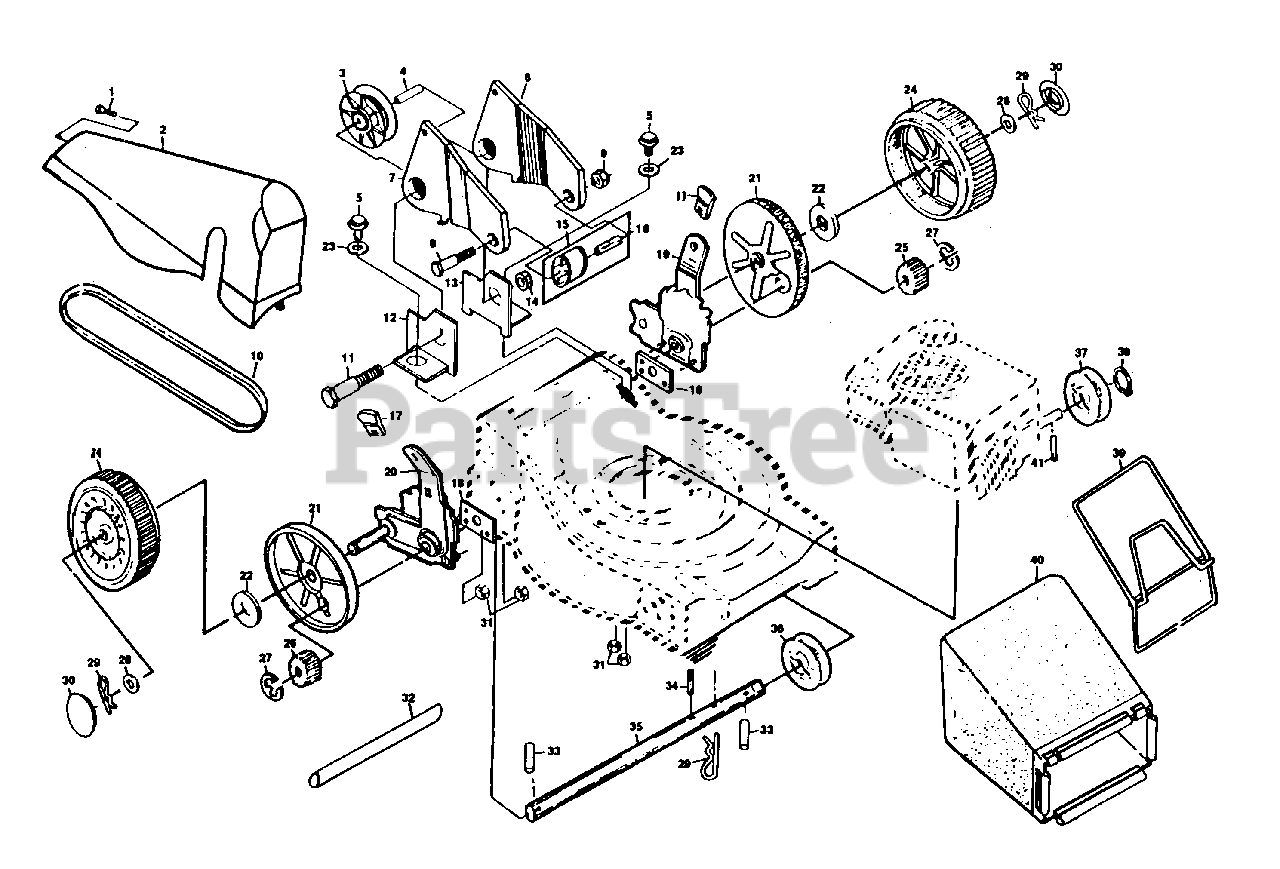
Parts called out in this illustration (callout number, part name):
1	Hex Washer Hd. Screw #10-24 x 1/2 (AYP part number)
2	Drive Cover (AYP part number)
3	Idler Pulley (AYP part number)
4	Pulley Spacer (AYP part number)
5	Screw Hex Hd. Mach. 1/4-20 x .75 (AYP part number)
6	Idler Bracket (Left) (AYP part number)
7	Idler Bracket (Right) (AYP part number)
8	Hex Head Bolt 1/4-20 x 1-1/2 (AYP part number)
9	Locknut 1/4-20 (AYP part number)
10	Drive Belt
11	Hex Head Bolt 5/16-18 x 1-1/2 (AYP part number)
12	Pivot Bracket (Right) (AYP part number)
13	Pivot Bracket (Left) (AYP part number)
14	Locknut 5/16-18 (AYP part number)
15	Idler Assembly Kit (Inc. 16)
16	Idler Spacer (AYP part number)
17	Selector Knob (AYP part number)
18	Spacer Plate (AYP part number)
19	Selector Assembly (Left)
20	Selector Assembly (Right)
21	Dust Cover
22	Washer (AYP part number)
23	Flat Washer (AYP part number)
24	Wheel & Tire Assembly 9.0 x 2.0 (AYP part number)
25	Drive Pinion (Left) (AYP part number)
26	Drive Pinion (Right) (AYP part number)
27	E-Ring (AYP part number)
28	Washer (AYP part number)
29	Retainer Clip (AYP part number)
30	Hubcap (AYP part number)
31	Locknut 1/4-20 (AYP part number)
32	Drive Shaft Cover (AYP part number)
33	Drive Pawl (AYP part number)
34	Roll Pin 3/16 x 7/8 (AYP part number)
35	Drive Shaft (AYP part number)
36	Driven Pulley (AYP part number)
37	Drive Pulley
38	Retaining Ring (AYP part number)
39	Catcher Frame Assembly (AYP part number)
40	Grass Bag Assembly
41	Dowel Pin (AYP part number)
